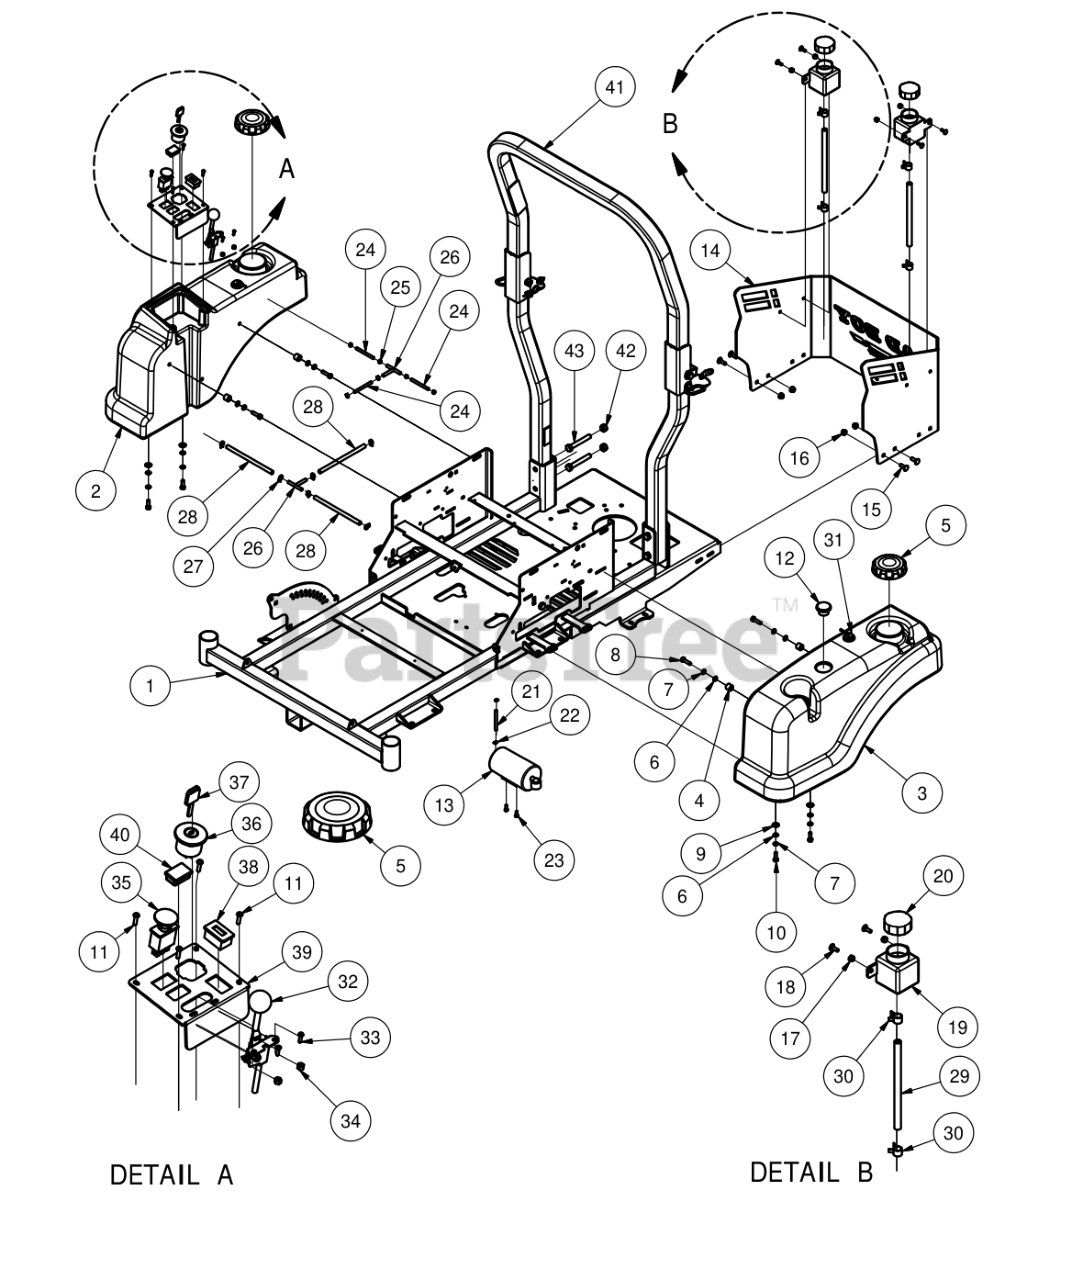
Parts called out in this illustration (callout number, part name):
1	2016 Compact Outlaw Frame
2	Right Fuel Tank/Outlaw/2012/EPA
3	Left Fuel Tank/Outlaw/2012/EPA
4	.380x.735x.470 Nylon Spacer
6	1/4" Flat Washer
7	5/16" Lock Washer
8	5/16 x 1 1/4 Hex Bolt
9	.360 ID Plastic Washer
10	5/16" x 1" Bolt
11	10-32 x 3/8" Button Socket Head Bolt
12	Fuel Gauge Tanks W/downtube
13	Carbon Canister
14	2014 ZT Rear Plate
15	5/16" x 1" Carriage Bolt
16	5/16" Nylock Flange Nut
17	1/4" Nylock Nut
18	1/4" x 3/4" Carriage Bolt
19	350ml Expansion Tank
20	Hydraulic Tank Cap
21	3/16 Vinyl Tubing
22	3/16" Vinyl Hose Clamp
23	M6-1.0 X 16MM Hex Bolt
24	1/4" Vinyl Tubing
25	1/4" Hose Clamp
26	fuel line T
27	1/4 Fuel Hose Clamp
28	1/4" Fuel Line Hose
29	3/8" Clear Hose
30	3/8" Hose Clamp
31	Rollover Valve
32	Throttle Lever Assembly
33	10-24 X 5/8 BS Button Head Bolt
34	10-24 Nylon Insert Locknut
35	PTO Switch
36	Ignition Switch
37	Ignition Key
38	Tachometer
39	Control Panel
41	2016 2X2 ROPS
42	1/2" Center Lock Nut
43	1/2-13 x 3 1/2 GR 5 Hex Bolt
